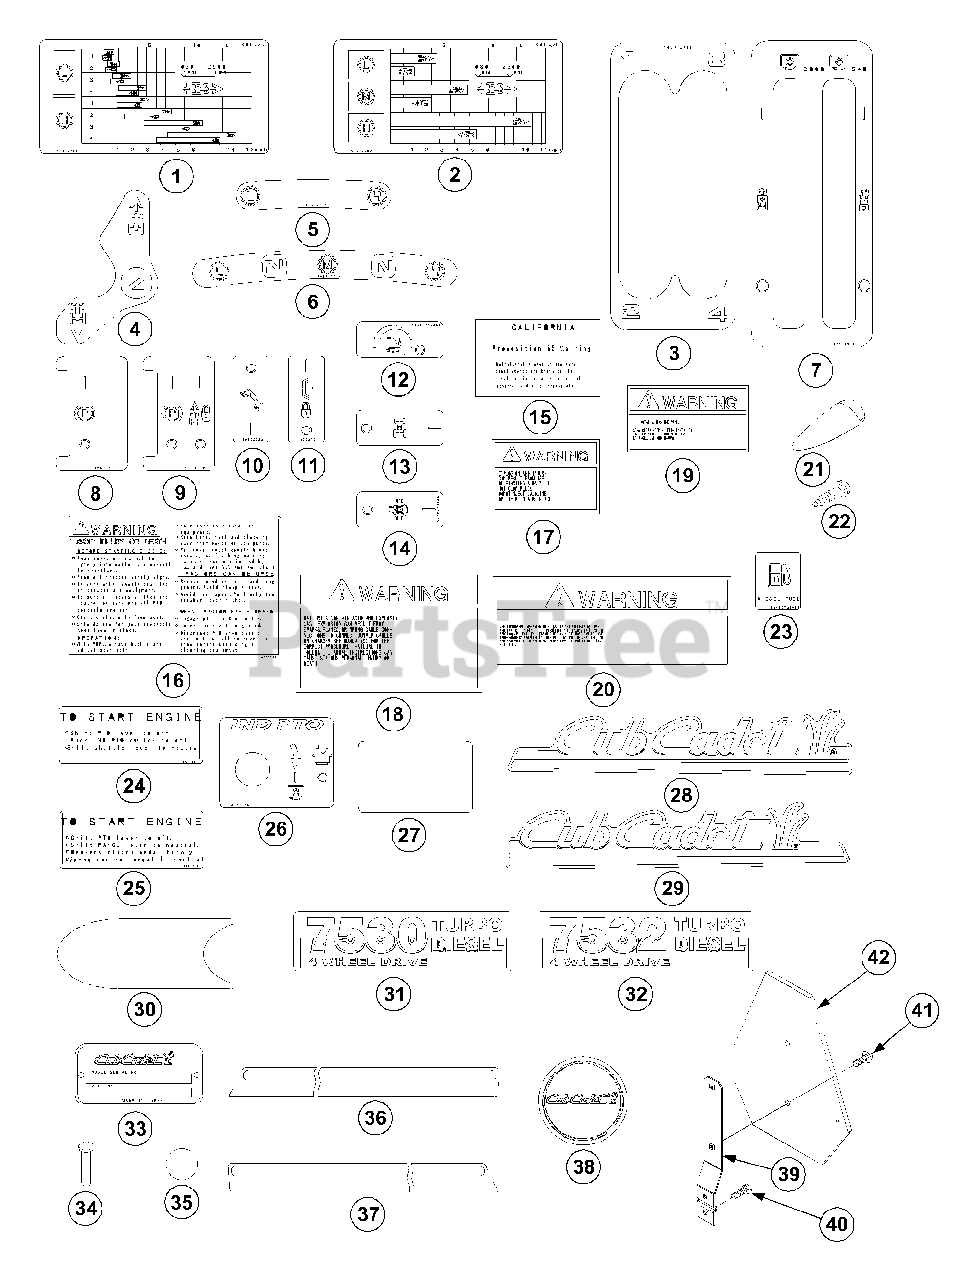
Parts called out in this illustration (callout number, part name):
1	Label Speed G
2	Label Speed H
4	Label Shuttle
6	Label Sub H
9	Label Brake-Sp
11	Label Declutch
12	Label D.R.Cont
14	Label Diff Lock
15	Label Propositi
16	Label,Warning
17	Label,Warning
18	Label,Warning
19	Label,Warning
20	Label Warning
22	Screw,Tapping
24	Label Start G
25	Label Start H
27	Mark
28	Label Side LH
29	Label Side RH
31	Label Model G
32	Label Model H
33	Name Plate
36	Label LH,Side
38	Label,Steering
40	Bolt,w/Washer
41	Screw,w/Washer
42	Emblem,SMV
